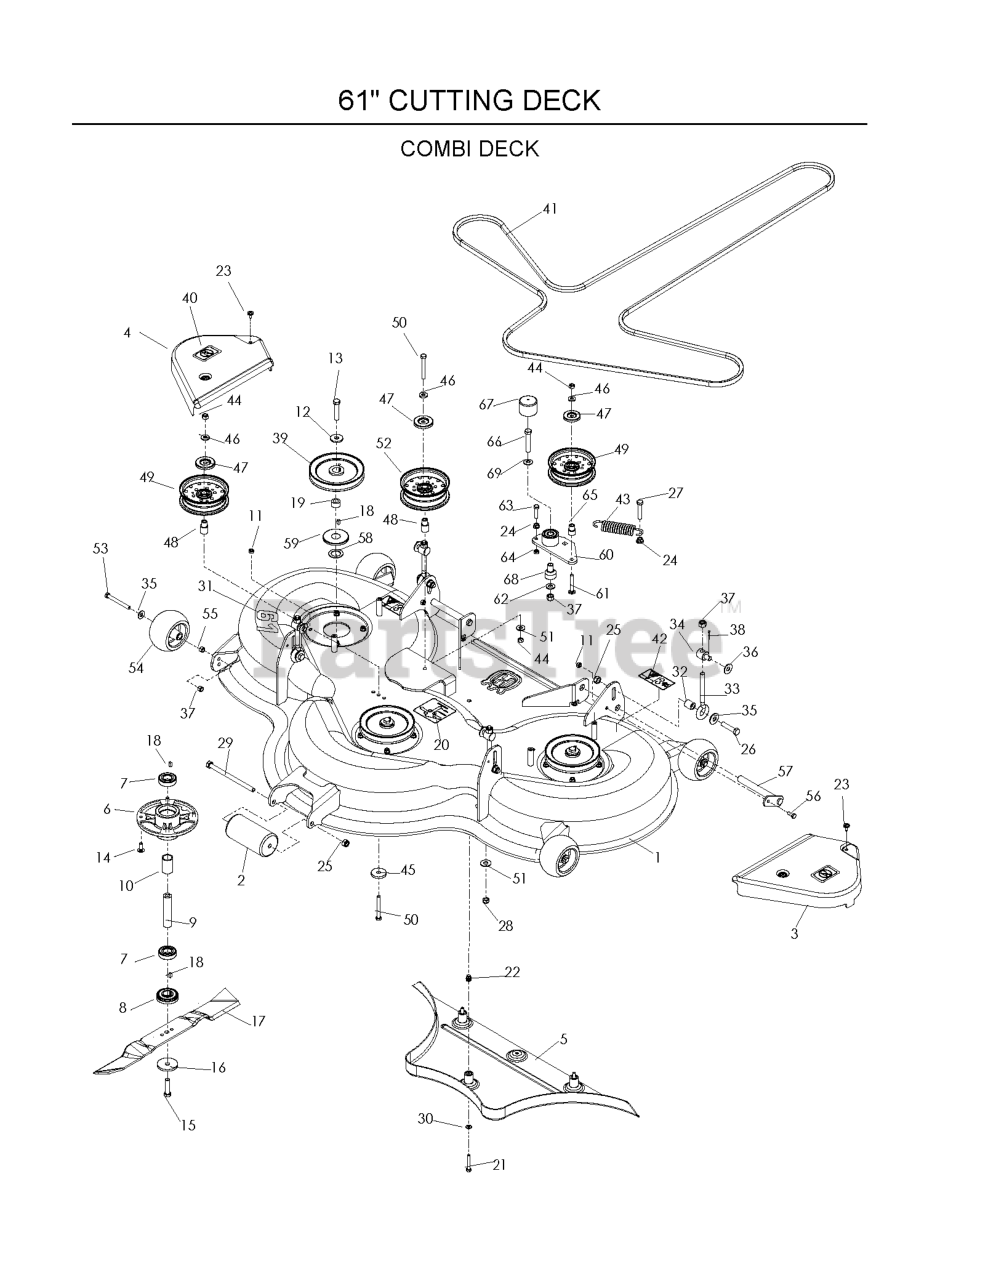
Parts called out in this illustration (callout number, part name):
1	DECK W/DECALS, 61" HUS
2	ROLLER
3	BELT SHIELD LT
4	BELT SHIELD RT
5	PLUG ASSEMBLY
6	BEARING HOUSING
7	BALL BEARING
8	BUSHING, BLADE
11	5/16-18 NYLOC FLANGE NUT
12	WASHER-.533IDX1.37OD
13	HCS M12 X 1.75 X 60 GR5 ZD
14	RHSNB 5/16C X 1
15	HCS M12 X 1.75 X 50 GR8.8 ZD
19	KEY RETAINER
20	DECAL, BELT ROUTING
21	HCS M8 X 1.25 X 50 GR8.8 ZD
22	BLIND RIVET NUT
23	SCREW 1/4 X 5/8
24	NUT 3/8C WHIZ
25	NUT 7/16C CENTERLOCK
26	HCS 7/16 - 14 X 1 3/4
27	HCS 3/8C X 2
28	NUT HEX 3/8-16 NYLON, THIN
29	HCS 7/16-14 X 7 GR5 ZD
30	FLAT WASHER 5/16 SAE
31	DECAL
35	WASH USS FLAT 1/2
36	WASHER 1/2 FLAT
37	NUT 1/2-13 HEX NYLOC ZD
38	PIN COTTER 1/8 X 1 ZD
39	PULLEY, 61
40	DECAL, NO STEP
41	DECK BELT, 61 CMB
42	DECAL, BELT DRIVE
44	NUT 3/8-16 NYLOC
45	SPINDLE WASHER
46	WASHER, 3/8 THICK
47	DUST SHIELD
48	IDLER BUSHING
49	IDLER PULLEY
50	SCREW 3/8C X 2 3/4 HEX CAP
51	WASHER 3/8 FLAT
52	IDLER PULLEY (TALL)
53	HCS 1/2-13 X 4 GR 5 ZD
54	GAUGE WHEEL
55	NUT HEX 1/2
56	HCS 5/16C X 1
57	PIN, STRUT, WELDMENT
58	WASHER-1.06IDX1.63ODX.06
59	BOTTOM DUST CAP
60	ARM-IDLER W/BRG
61	CARRIAGE BOLT 3/8-16 X
62	WASHER 1/2" FLAT
63	HCS 3/8-16 X 1-1/2
64	NUT 3/8-16 HEX JAM
65	BUSHING, IDLER
66	HCS 1/2C X 2 3/4
67	CAP, VINYL
68	PIVOT, BEARING
69	CONTACT BELLSPR 1/2
